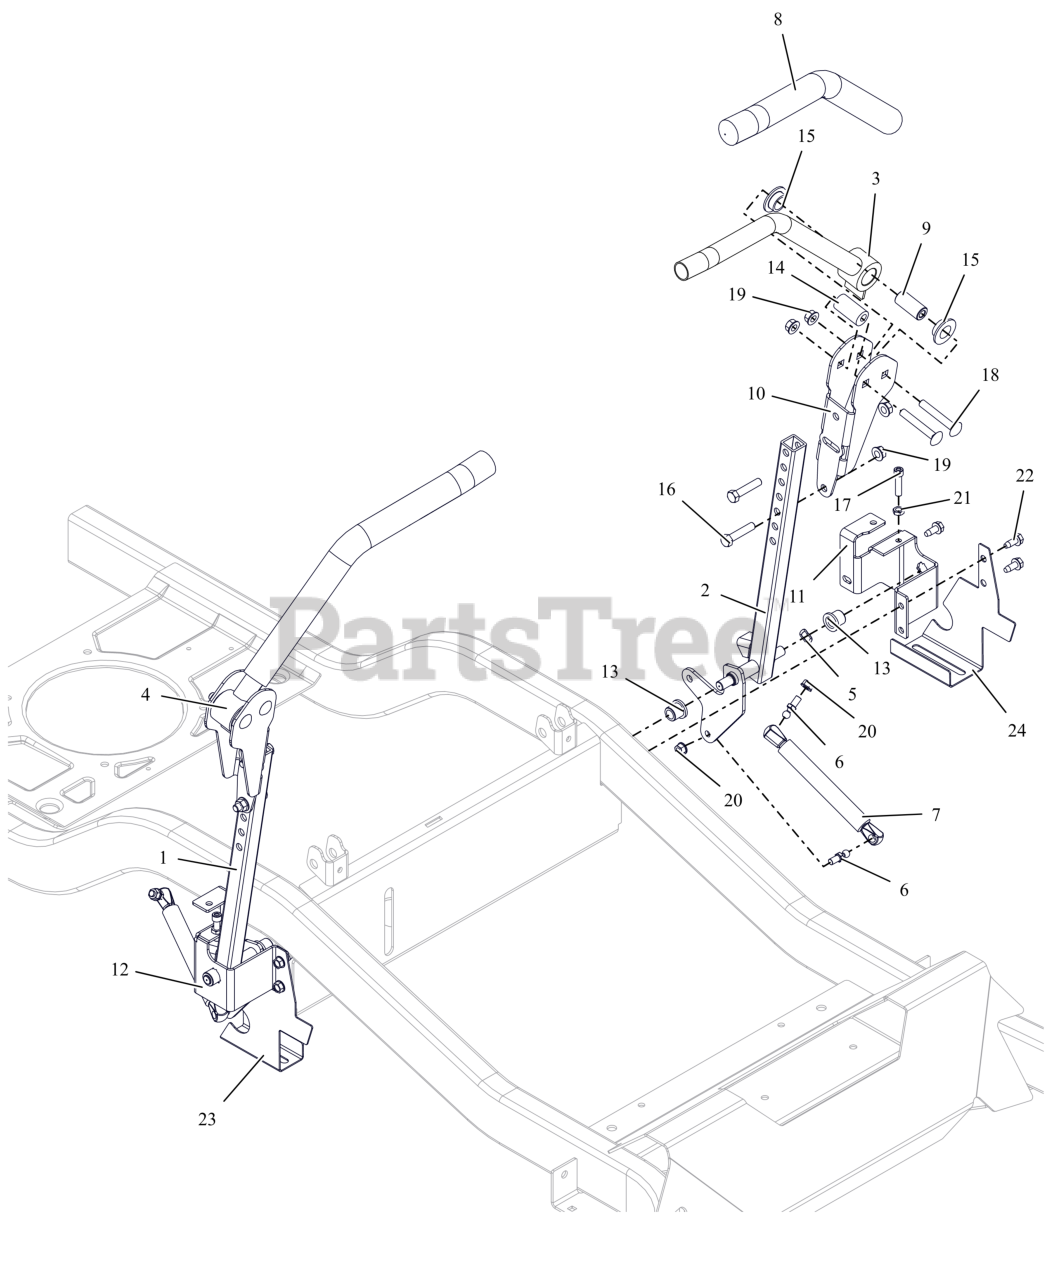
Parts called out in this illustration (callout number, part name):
1	WLDMT, STEERING RH
2	WLDMT, STEERING LH
3	WLDMT, CONTROL HANDLE- BLK
4	WLDMT, CONTROL HANDLE- BLK
5	WAVE WASHER .531X.781X.125FH
6	STUD- BALL
7	DAMPER
8	GRIP, HANDLEBAR
9	SPACER, STEERING ARM
10	ADJ UPPER CONTROL ARM BRKT-BLK
11	BRKT, STEERING ARM MOUNT -LH
12	BRKT, STEERING ARM MOUNT -RH
13	BHSG-FLG .500X.750X.750X.125
14	BSHG, ECCENTRIC.406X.875X1.625
15	BSHG-FLG .762X1.48X.44 NYL
16	BLT, HEX .38-16X1.75 G5 ZCC
17	BLT, SHCS .312-18X1.25 G8 SS
18	BLT, RHSSN.38-16X2.50 G5 ZCC
19	NUT-LK-TOP-FLG .38-16 ZC120
20	NUT,LK-CTR-FLG .31-18 GF ZCC
21	NUT-JAM .312-18 G2 ZCC
22	SCR,TAP .312-18X.75 HWH TR ZCC
23	GUARD, FRAME RAIL BELT-RH (BLACK)
24	GUARD, FRAME BELT GUARD LH (BLACK)
